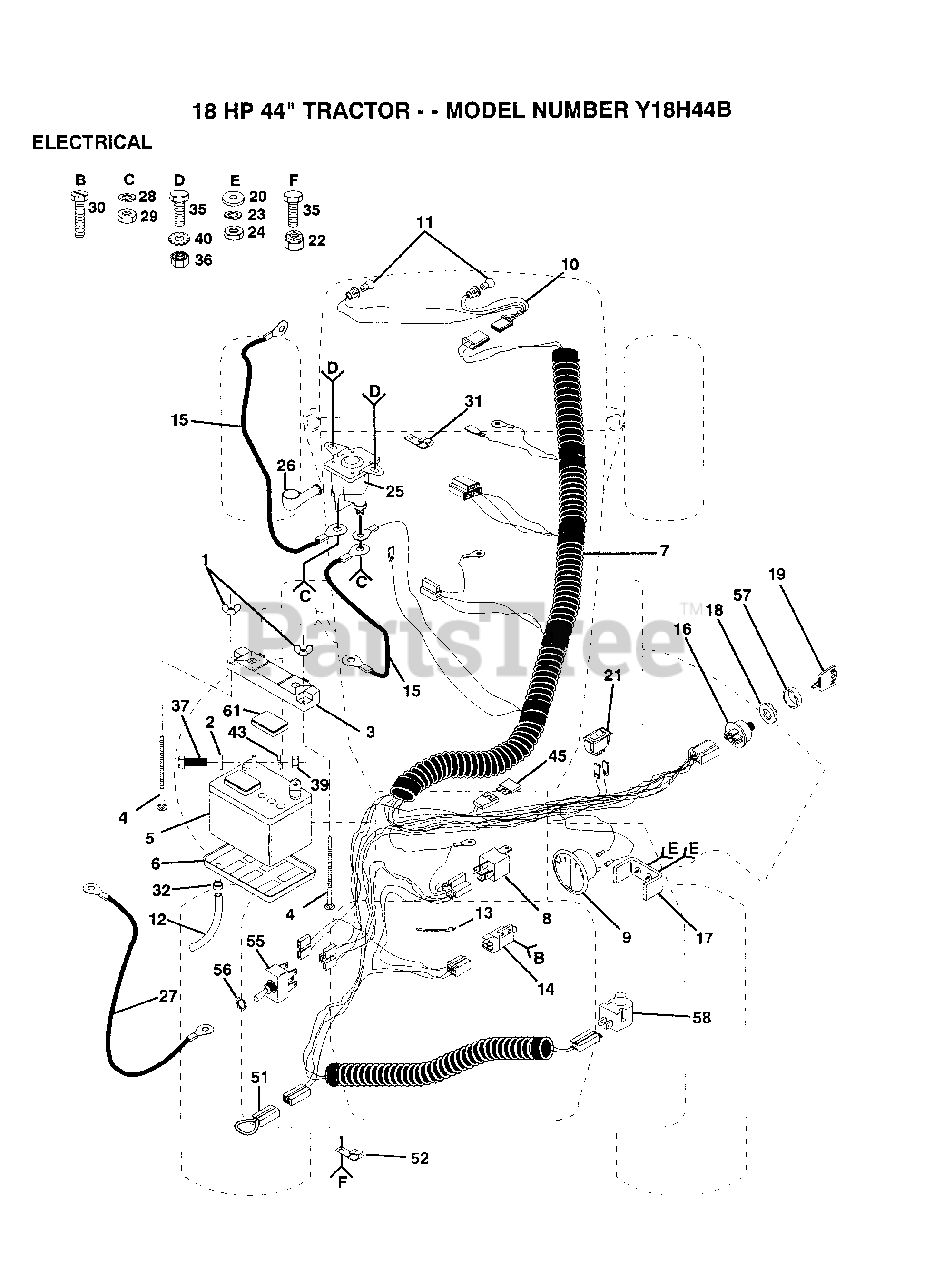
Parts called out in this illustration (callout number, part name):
2	WASHER
4	BOLT
6	"TRAY T, BATTERY"
8	RELAY ASSY T
9	AMMETER T
13	WIRE TIE
14	SWITCH INTERLOCKT
15	CABLE-BATTERY T
18	NUT IGNITION
19	KEY
20	WASHER
21	SWITCH LT
27	CABLE T
29	NUT
30	SCREW
31	CLIP T
32	HOSE CLAMP T
35	BOLT
36	NUT
37	BOLT LT
43	LOCKWASHER
45	FUSE HYT
52	CLIPT
56	HEX NUT T
58	SWITCH SEAT
61	"CAP,BATTERY "
